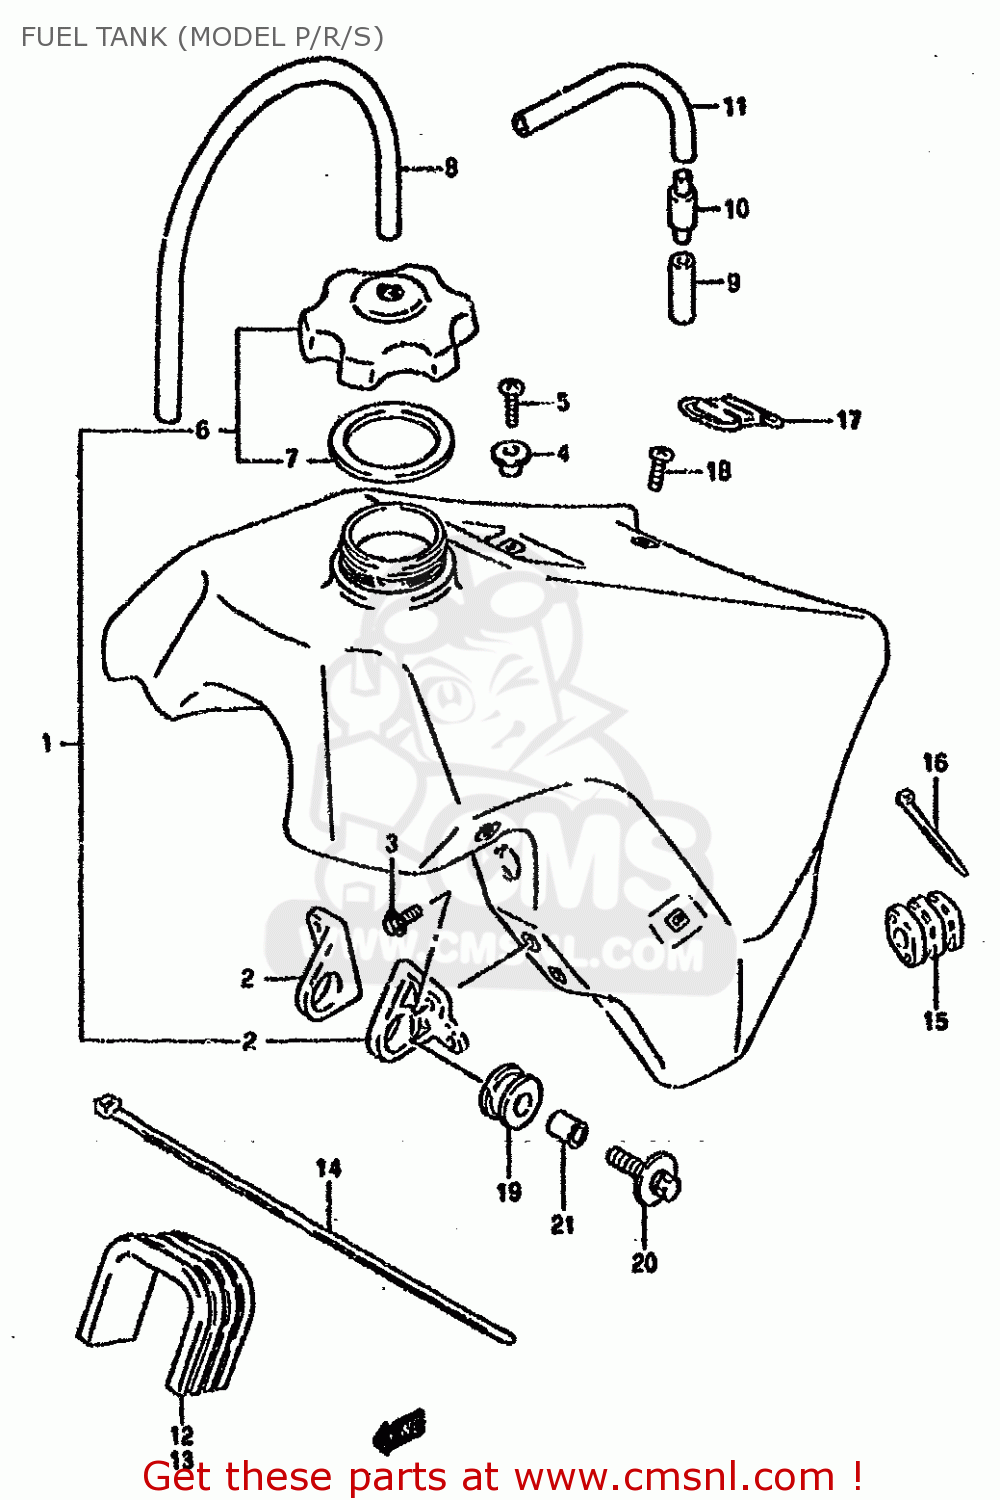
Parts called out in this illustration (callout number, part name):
1	TANK SET,FUEL
2	BRACKET,FUEL TANK FR
3	BOLT
4	HOOK,SEAT FR
5	SCREW
6	CAP SET,FUEL TANK
7	GASKET,CAP (NAS)
8	HOSE(5X8.2X600)
9	HOSE(5X8.2X600)
10	PLUG,FUEL TANK BREATHER
11	HOSE(5X8.2X600)
12	CUSHION,FUEL TANK NO.2
13	CUSHION,FUEL TANK
14	CLAMP(L:300)
15	CUSHION,FUEL TANK NO.2
16	CLAMP(L:145)
17	BAND,FUEL TANK RR
18	SCREW
19	CUSHION,MUFFLER
20	BOLT(6X30)
21	SPACER (6.4X9X13.5)
